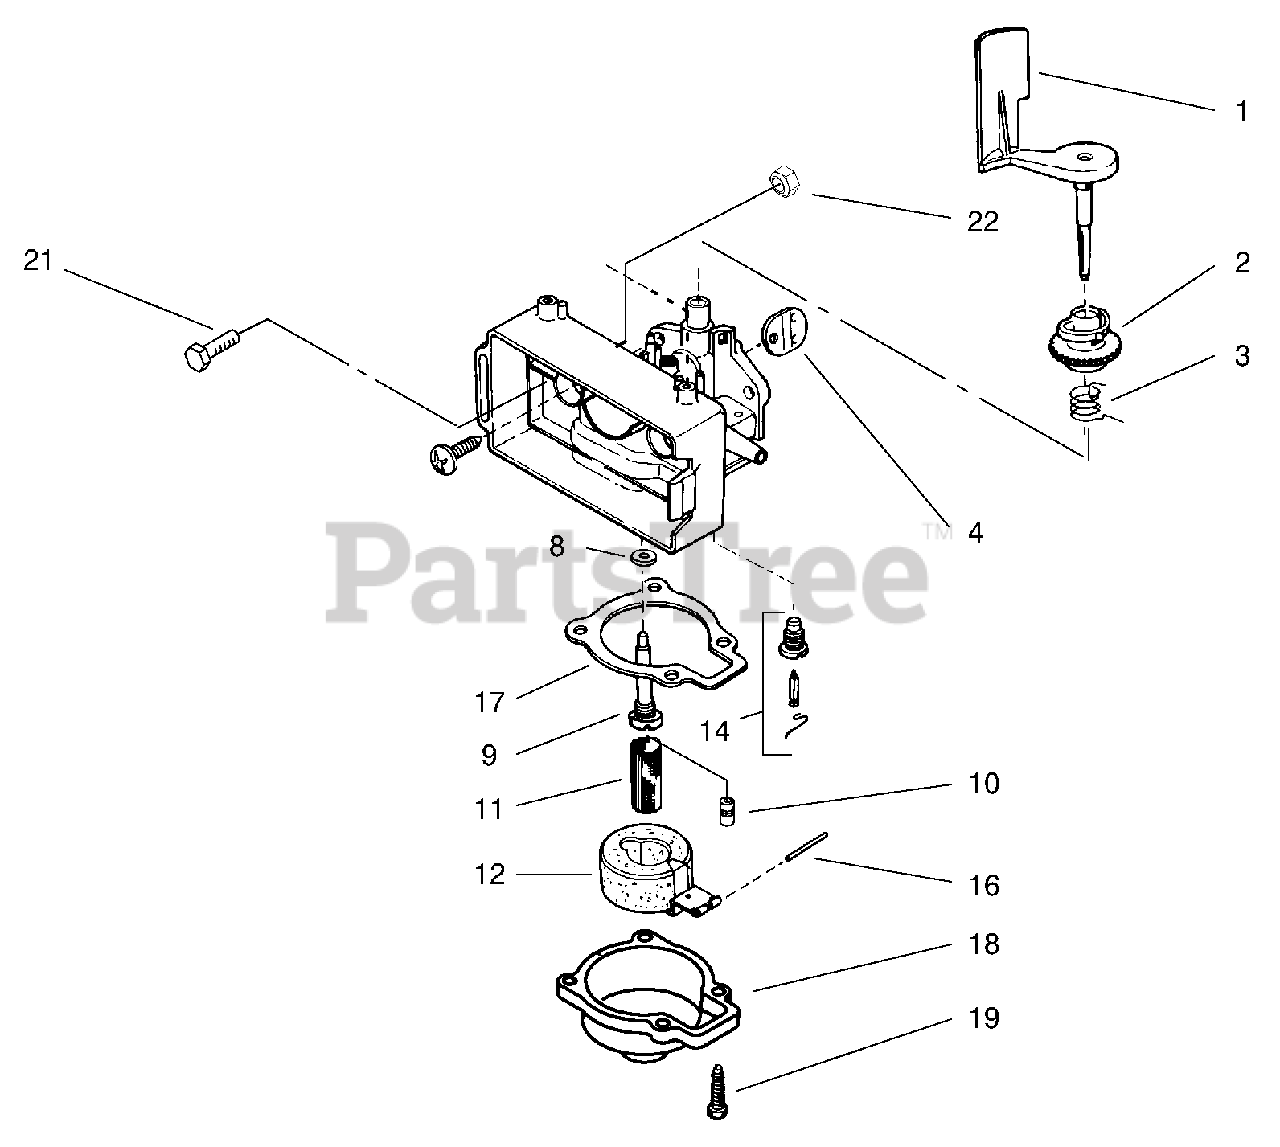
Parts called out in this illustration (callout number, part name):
1	Air Vane & Shaft
2	Collar-Adjust, Airvane
3	Spring,Throttle
4	Disc-Thro.
10	Main Jet
11	Filter-Fuel
12	Float & Arm Ay
14	Valve/Seat-Float
16	Pin-Straight
18	Chamber-Float
19	Screw-HH
22	Nut-Hex
